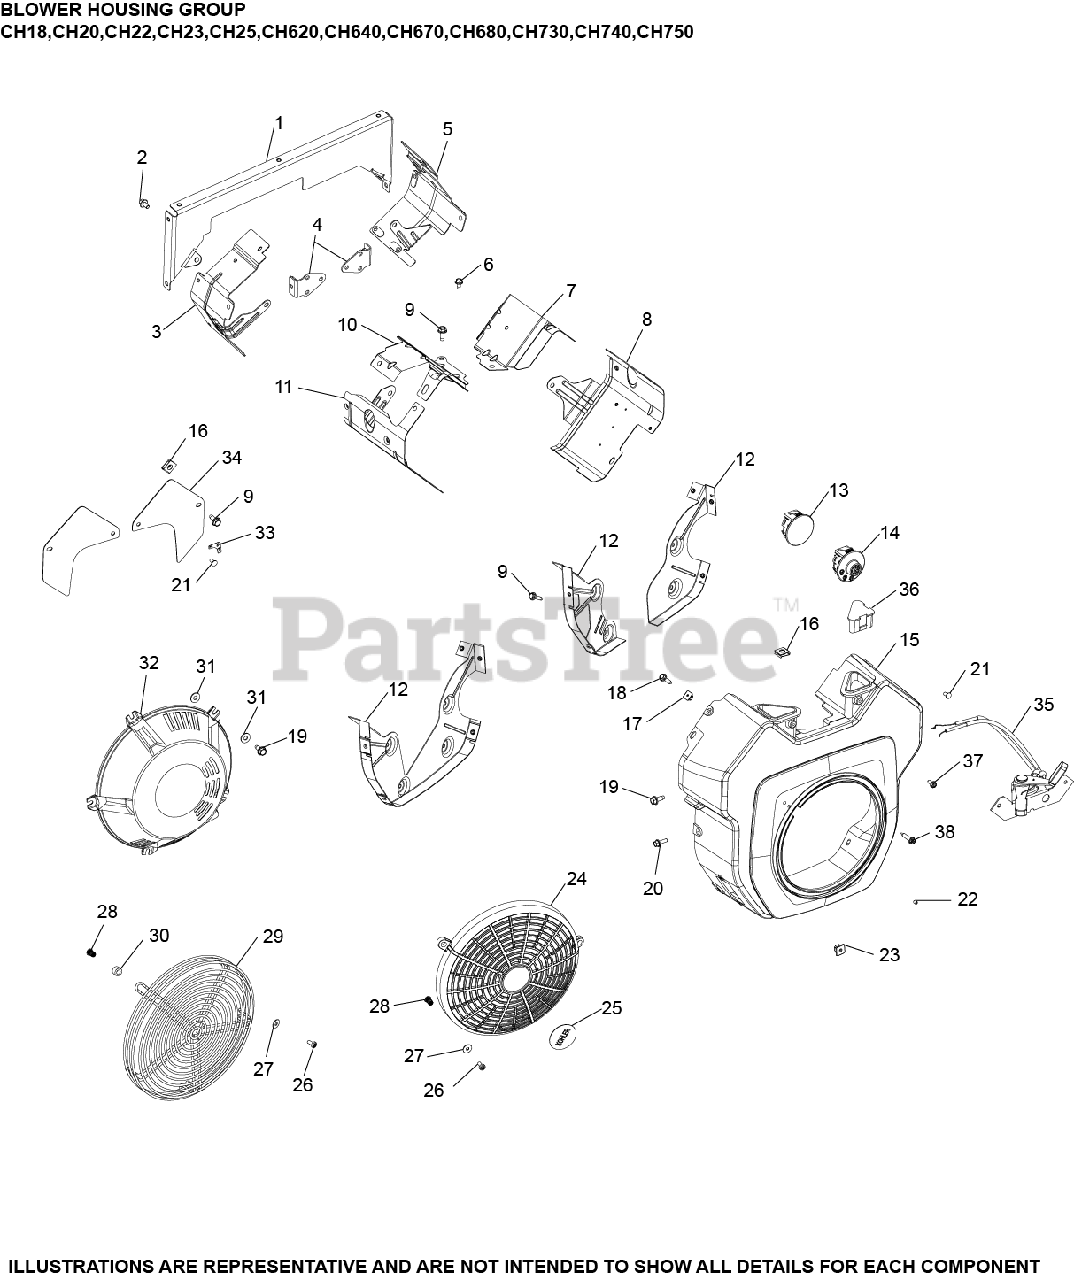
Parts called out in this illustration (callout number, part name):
6	SCREW, THREAD FORMING
7	BAFFLE, VALLEY (CH)-USE 24 063 93-S
8	KIT, CYL BAFFEL #1 SIDE
9	SCREW, THREAD FORMING
10	BAFFLE, VALLEY #2 SIDE-USE 24 063 94-S
11	KIT, CYL BAFFEL #2 SIDE
12	PLATE, BACKING-USE 24 146 59-S
15	HOUSING, BLOWER
16	CLIP, MOUNTING-USE 25 154 13-S
19	SCREW, THREAD FORMING
24	KIT, FIXED GUARD
28	INSERT, THREADED USE 25 332 19-S
34	KIT, ACCESS PANEL
